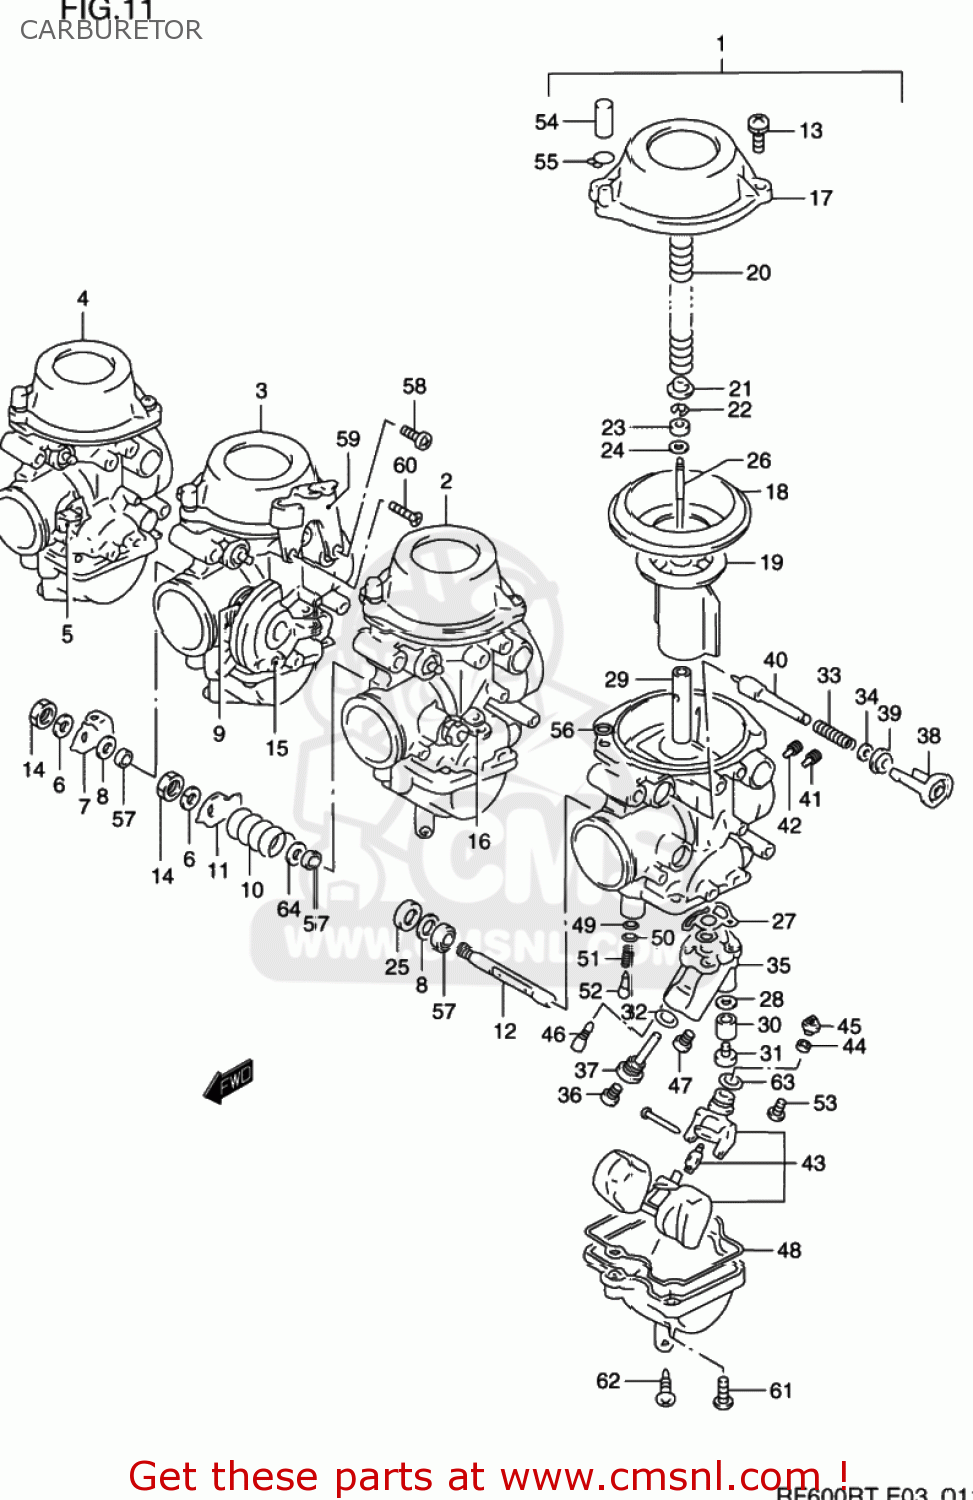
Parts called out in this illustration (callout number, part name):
1	CARBURETOR ASSEMBLY,LEFT
2	CARBURETOR ASSEMBLY,MIDDLE,LEFT
3	CARBURETOR ASSEMBLY,MIDDLE,RIGHT
4	CARBURETOR ASSEMBLY,RIGHT
5	SHAFT,THROTTLE
6	WASHER,LOCK
7	LEVER,THROTTLE
8	GASKET,THROTTLE SHAFT (NAS)
9	SPRING
10	SPRING
11	SHAFT,THROTTLE
12	SHAFT,THROTTLE
13	SCREW
14	NUT
15	SHAFT,THROTTLE
16	LEVER,THROTTLE
17	COVER,DIAPHRAGM
18	DIAPHRAGM
19	VALVE,PISTON
20	SPRING
21	RING
22	E RING
23	RING
24	WASHER
25	RING
26	NEEDLE JET (5E97-1)
27	O RING
28	GASKET (NAS)
29	JET,NEEDLE(O-9)
30	RING
31	SCREW
32	O RING
33	SPRING
34	WASHER
35	JET BLOCK ASSEMBLY
36	JET
37	HOLDER,JET
38	HOLDER,GUIDE
39	CAP,STARTER
40	PLUNGER ASSY
41	JET,AIR(0.6)
42	JET,AIR
43	FLOAT/NEEDLE VALVE ASSEMBLY
44	RING
45	FILTER
46	JET,PILOT(15)
47	JET,STARTER(47.5)
48	SEAL
49	O RING,PILOT AIR SCREW
50	WASHER
51	SPRING
52	SCREW,PILOT
53	SCREW
54	CAP
55	CLIP
56	O RING
57	SEAL
58	SCREW
59	BRACKET
60	SCREW
61	SCREW
62	SCREW,DRAIN
63	O-RING,NEEDLE VALVE
64	RING
